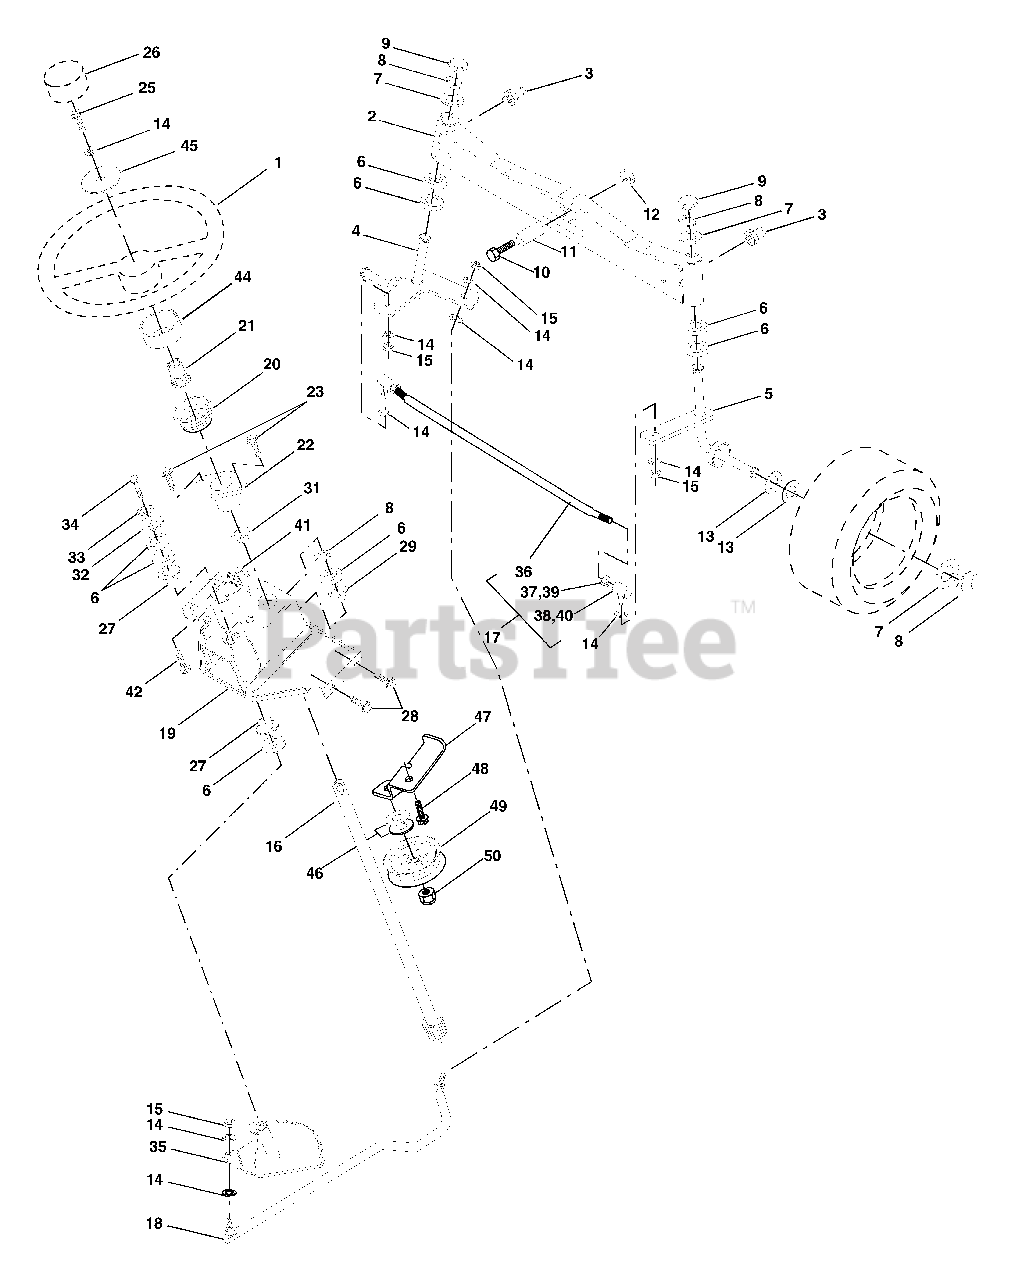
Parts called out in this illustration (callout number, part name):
1	Wheel, Steering
2	Axle Asm., Front
3	Fitting, Grease
4	Spindle Asm, LH
5	Spindle Asm., RH
6	Bearing, Race Thrust Harden
7	Washer 25/32 x 1-5/8 x 16 Ga.
8	Ring, Klip #T5304-75
9	Cap, Spindle
10	Bolt, Fin Hex 5/8-11 x 2-3/4
11	Spacer Brg Axle Front 1.570
12	Nut, Lock Flange 5/8-11 Unc
13	Washer 25/32 x 1-1/4 x 16 Ga.
14	Washer, Lock Hvy Hlcl Spr 3/8
15	Nut Lock Center 3/8-24 Unf
16	Shaft Asm., Steering
17	Rod Asm., Tie Ball J Ball Vgt
18	Draglink, Ball Joint Solid Vgt
19	Support Asm., Steering Vgt
20	Boot Steering
21	Adapter, Wheel Steering
22	Bushing, Strg.
25	Bolt, Fin Hex 3/8-16 x 1 Gr. 5
26	Cap , Wheel Steering
27	Bearing, Col. Strg.
28	Screw 3/8-16 x 3/4
29	Bearing, Flange
31	Bushing, Nyliner Snap
32	Washer 11/32 x 1 x 10 Ga.
33	Washer, Lock Hvy Hlcl Spr 5/16
34	Bolt, Hex Hd 5/16-18 x 3/4
35	Gear, Sector Steering
36	Tie Rod
37	Jam Nut RH Thread
38	Joint Asm. Ball RH Thread
39	Nut Hex Jam 3/8-24 UNF LH
40	Joint Asm Ball LH
41	Bracket Switch Inerlock VGT97
42	Screw 5/16-18 x 1/2
44	Extension Steering Premium
45	Washer 13/32 x 1-1/20 x 11 Ga.
46	Washer 13/32 x 1 x 10 Ga.
47	Bracket Asm. Idler
48	Screw 3/8-16 x .75
49	Pulley Idler Flat
50	Nut Lock Flg 3/8-16 Unc
